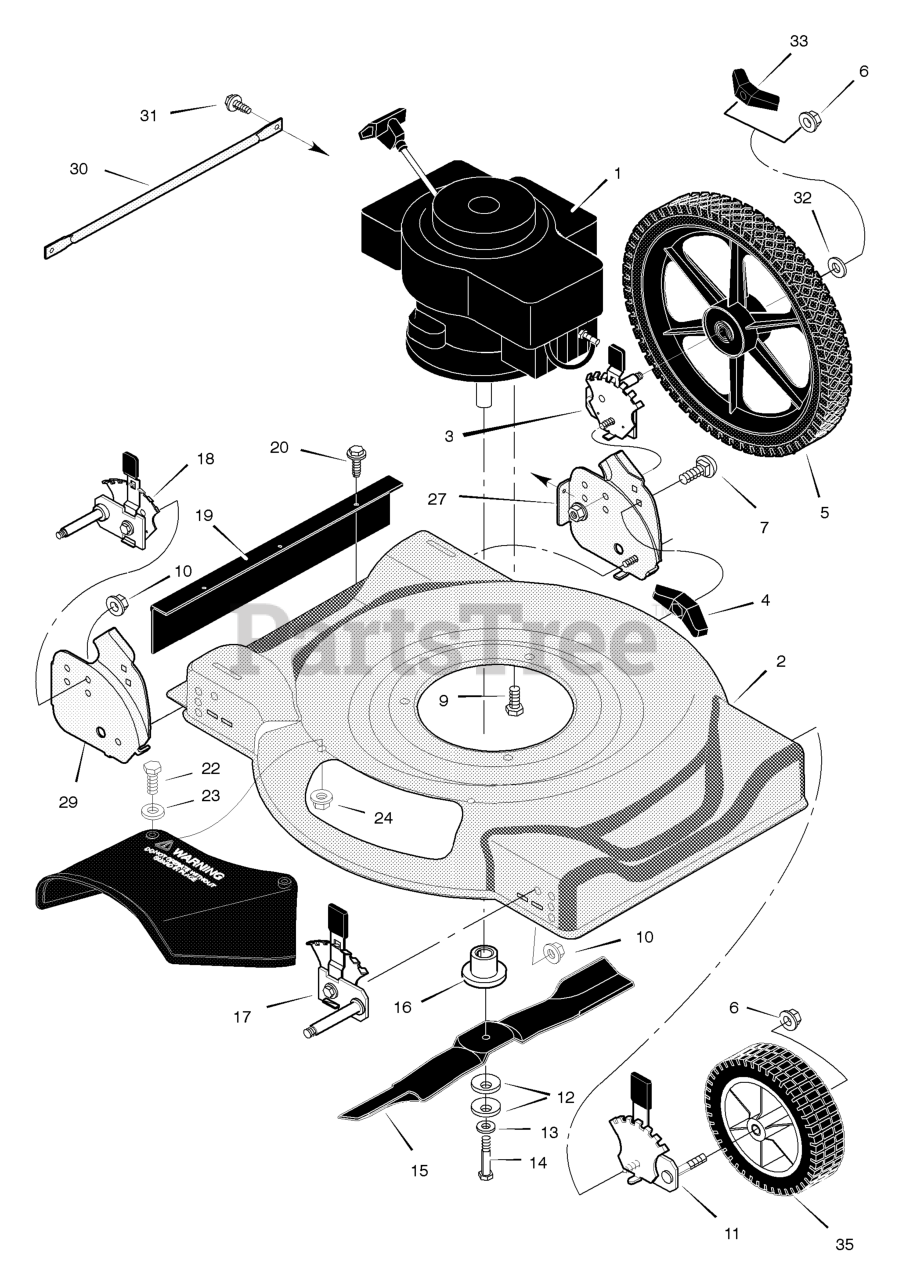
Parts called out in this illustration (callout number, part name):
1	Engine *
2	Housing
3	Height Adjuster, Left Rear
5	Wheel and Tire
6	Locknut, Flange
7	Bolt, Carriage
9	Bolt, Engine
10	Nut
11	Height Adjuster, Left Front
12	Washer, Belleville
14	Bolt, Hex
16	Adapter, Blade
17	Height Adjuster, Right Front
18	Height Adjuster, Right Rear
19	Guard, Rear
21	Deflector, Chute
23	Washer
24	Nut
27	Bracket, Left Handle
29	Bracket, Right Handle
33	Knob, Wing
35	Wheel and Tire
